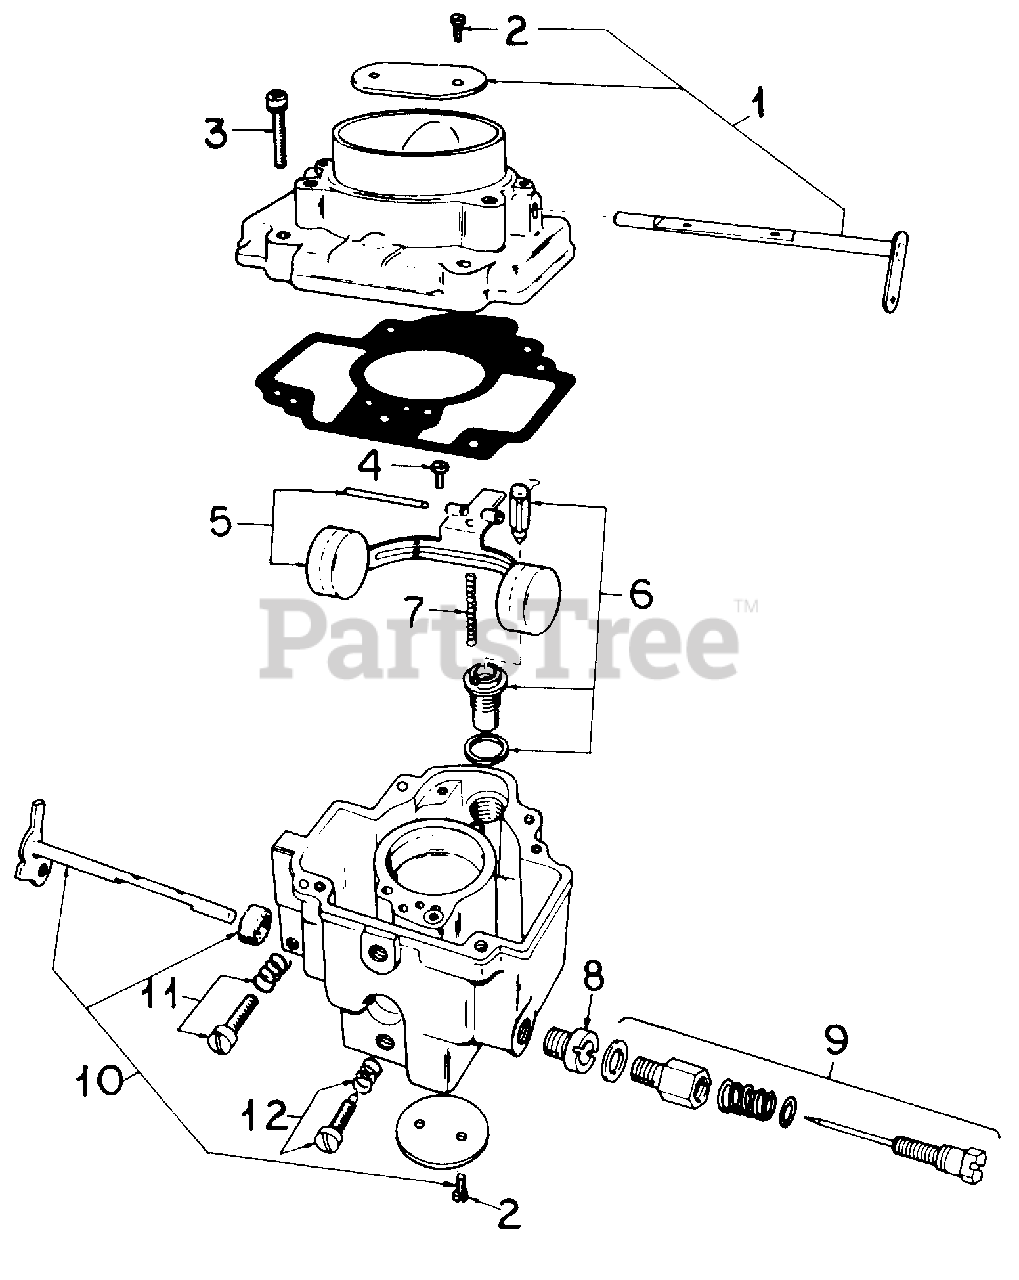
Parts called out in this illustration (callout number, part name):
1	Shaft, Choke
2	Screw, Choke Valve
3	Screw, Body to Intake
6	Valve & Seat Assy
7	Not used in this application
9	Needle Assy, Power
10	Package, Throttle Shaft
11	Package, Idle Speed Adj Screw
12	Package, Idle Needle
